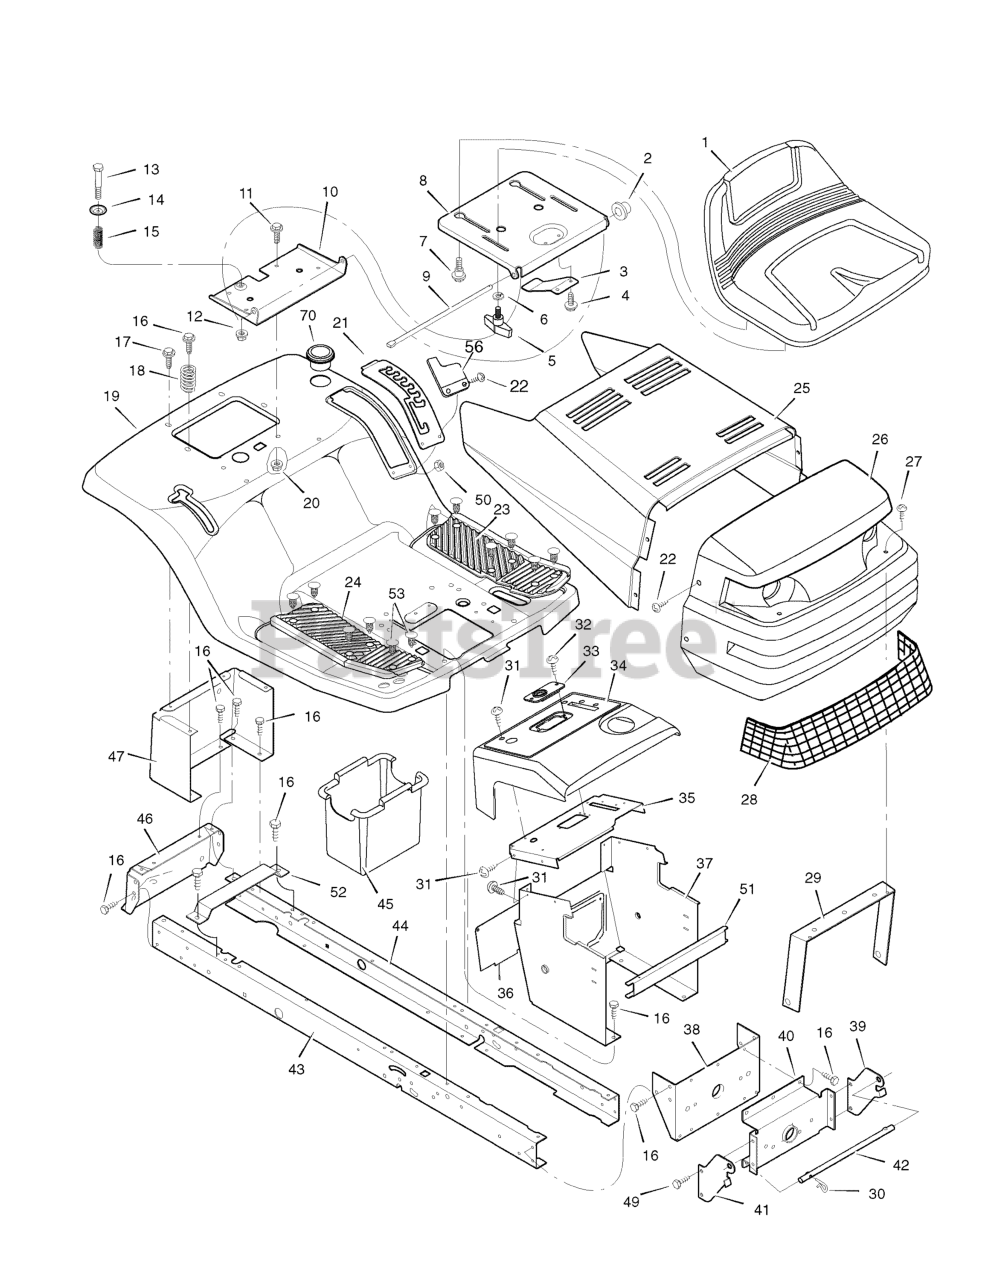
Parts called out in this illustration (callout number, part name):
1	Seat
2	Cap, Push 0n
5	Bolt, Wing
6	Washer
7	Bolt, Shoulder
8	Support, Seat
9	Rod, Pivot
10	Bracket, Pivot
11	Bolt
13	Bolt, Shoulder
19	Deck, Seat
20	Nut
21	Plate, Index
23	Mat, Left
24	Mat, Right
29	Brace, Grille
30	Pin, Hair
33	Bearing, Steering
35	Plate, Dash
36	Panel, Access
37	Support, Dash
38	Bracket, Rear Hanger
39	Support, Left Grille
40	Axle, Hanger
41	Support, Right Grille
42	Rod, Pivot
43	Frame, Right
44	Frame, Left
45	Container, Battery
46	Plate, Hitch
47	Panel, Rear
52	Support, Battery
53	Fastener, Panel
56	Support, Battery
70	Holder, Cup
